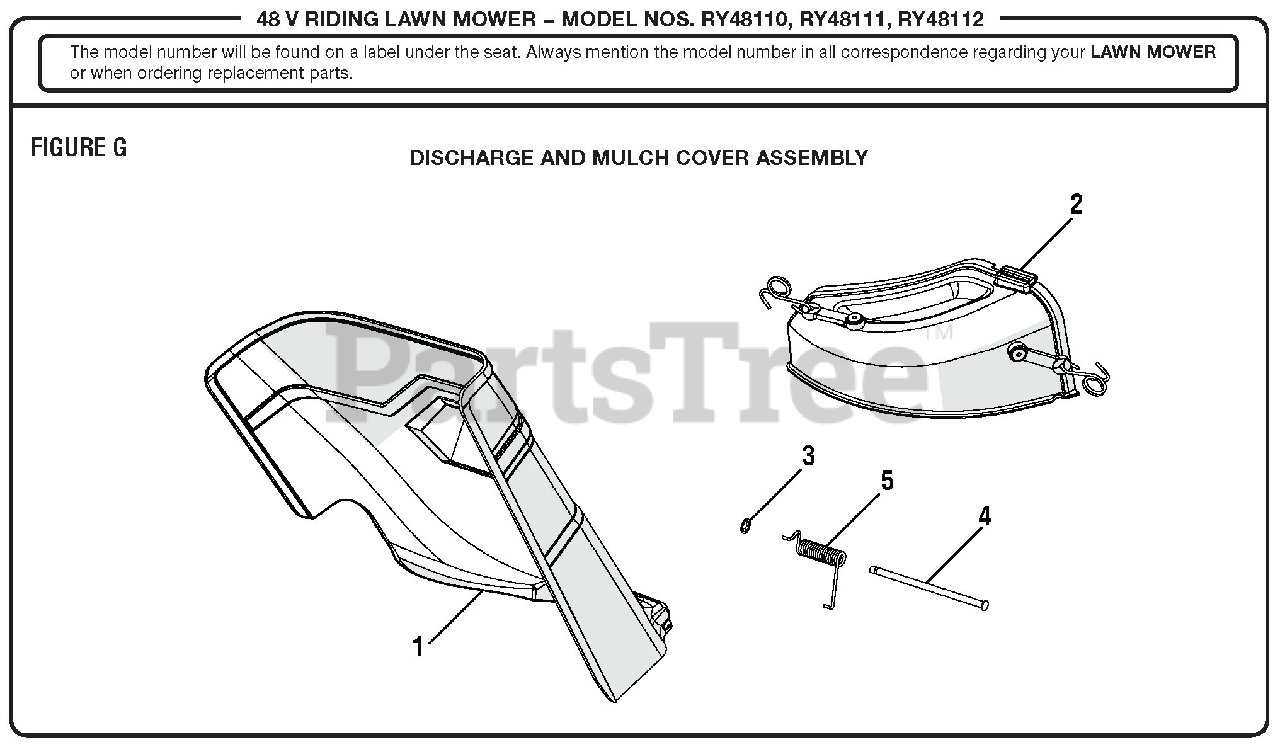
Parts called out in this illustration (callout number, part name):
1	Grass Deflector
2	Mulch Cover Kit
3	Retainer Clip
4	Hinge Pin (7.85 x 175.85)
5	Torsion Spring (19 x 62 x 3.02t)
